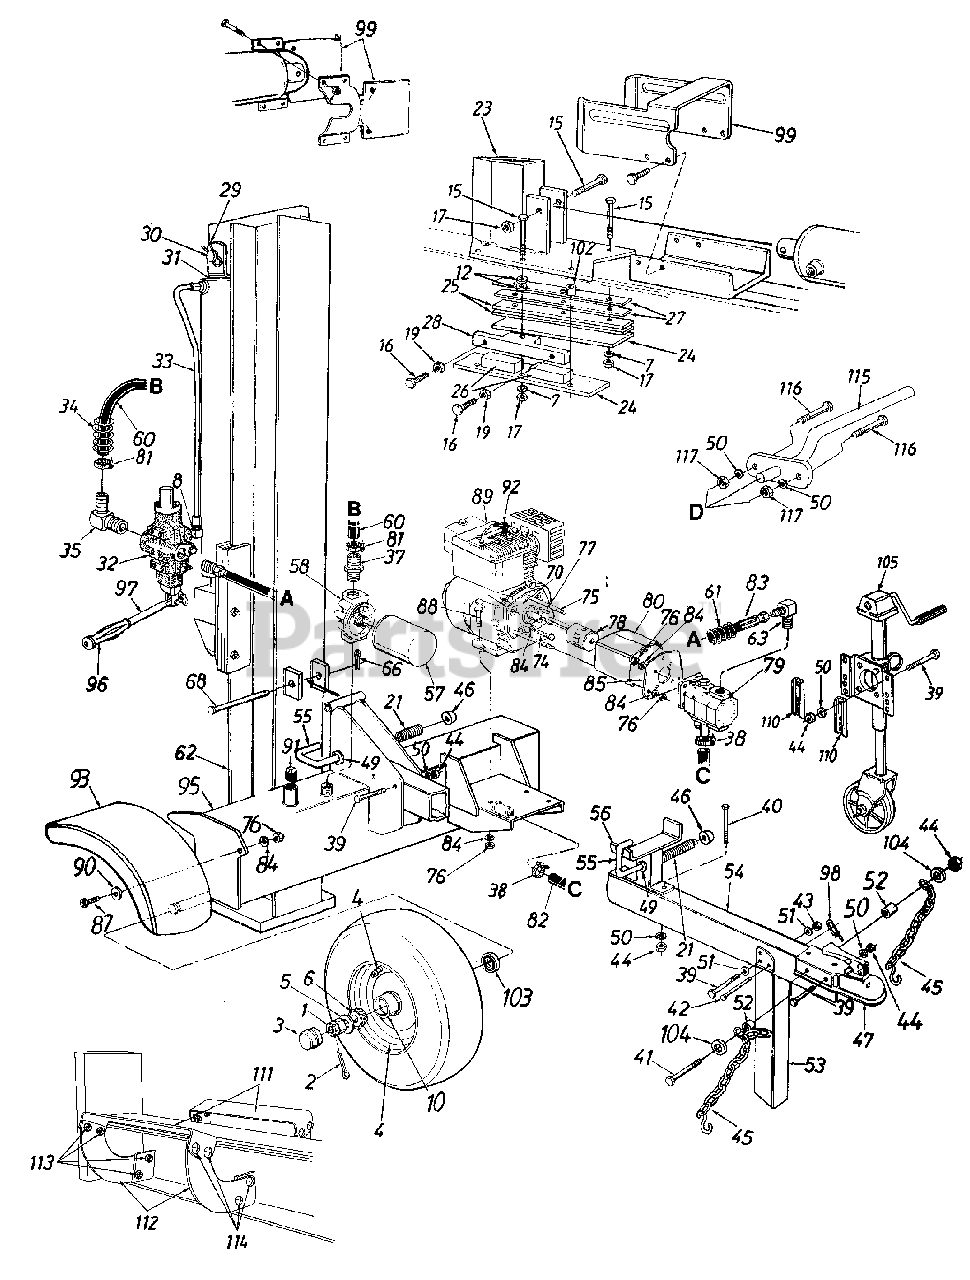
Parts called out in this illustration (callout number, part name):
1	Slotted Nut 3/4-16 Thd.
2	Cotter Pin 5/32" Dia.
3	Hub Cap
5	Fl-Wash. .76" I.D. x 1.5" O.D.
6	Bearing Cone
7	L-Wash. 1/2" I.D.
8	90 degree Solid Male Adapter
10	Bearing Cup
12	Hex Cap Scr. 3/8-16 x 1" Lg.
15	Hex Bolt 1/2-20 x 2.75" Lg.(Grd 8)
16	Hex Bolt 3/8-24 x 1.5" Lg.
17	Hex L-Nut 1/2-20 Thd.
19	Hex Jam Nut 3/8-24 Thd.(Grd 5)
21	Comp. Spring 4" Lg.
29	Cotter Pin
30	Cylinder Mounting Pin
31	Kit Seal 5.0" for Best Metals cylinder 718-0313
31	Hydraulic Cylinder
31	Kit Seal 5.0" for XINGHUI cylinder 718-0313A
31	Kit Seal 5.0" for ENERGY cylinder 718-0313A
33	Metal Pressure Tube
34	Hose Guard
35	Return Elbow
37	3/4" Hose Barb.
38	Hose Clamp 1.5" O.D.
39	Hex Bolt 3/8-16 x 3" Lg. (Grade 8)
40	Hex Bolt 3/8-16 x 4.75" Lg.
41	Hex Bolt 3/8-16 x 4.25" Lg.
44	Lock Nut 3/8-16 (585)
45	Chain-Tow Hitch
46	Push Cap
47	Hitch Coupler
49	Fl-Wash. .635" I.D. x .93" O.D.
50	L-Wash. 3/8" I.D.
52	Spacer .445" Lg.
55	Locking Rod
57	Filter Element
58	Filter Head
60	Return Hose 3/4" I.D. x 44" Lg.
61	Hose Guard
66	Cotter Pin 1/8" Dia.
68	Hinge Pin 1/2 x 4.8" Lg.
74	Hex Bolt 5/16-24 x .62" Lg.
75	Hex Bolt 5/16-24 x 5.25" Lg.
76	Hex Nut 5/16-24 Thd.
77	Sq.-Key 1/4" x 2" Lg.
78	Flexible Coupling
79	Gear Pump
80	Coupling Shield
81	Hose Clamp 5/8"
82	Suction Hose 1" I.D.
83	High Pressure Hydraulic Hose
84	L-Wash. 5/16" I.D.
87	Hex Bolt 5/16-24 x .75" Lg.
88	Hex Bolt 5/16-24 x 1.75" Lg.
89	Engine
90	Fl-Wash. .344" I.D. x .875" O.D.
91	L-Vent Pipe Plug
92	Spark Plug Boot
97	Control Handle
98	Hex Lock Nut 3/8-16
100	Hex Screw 3/8-16 x 2.0 Lg.
102	Spacer 1/2" I.D. x .86" Lg.
103	Bearing Seal Only
104	Fl-Wash. 3/8" I.D. x .87" O.D.
105	Jack Stand
114	Carriage Bolt 3/8-16 x 1" Lg.
117	Hex Nut 3/8-16 Thd.
